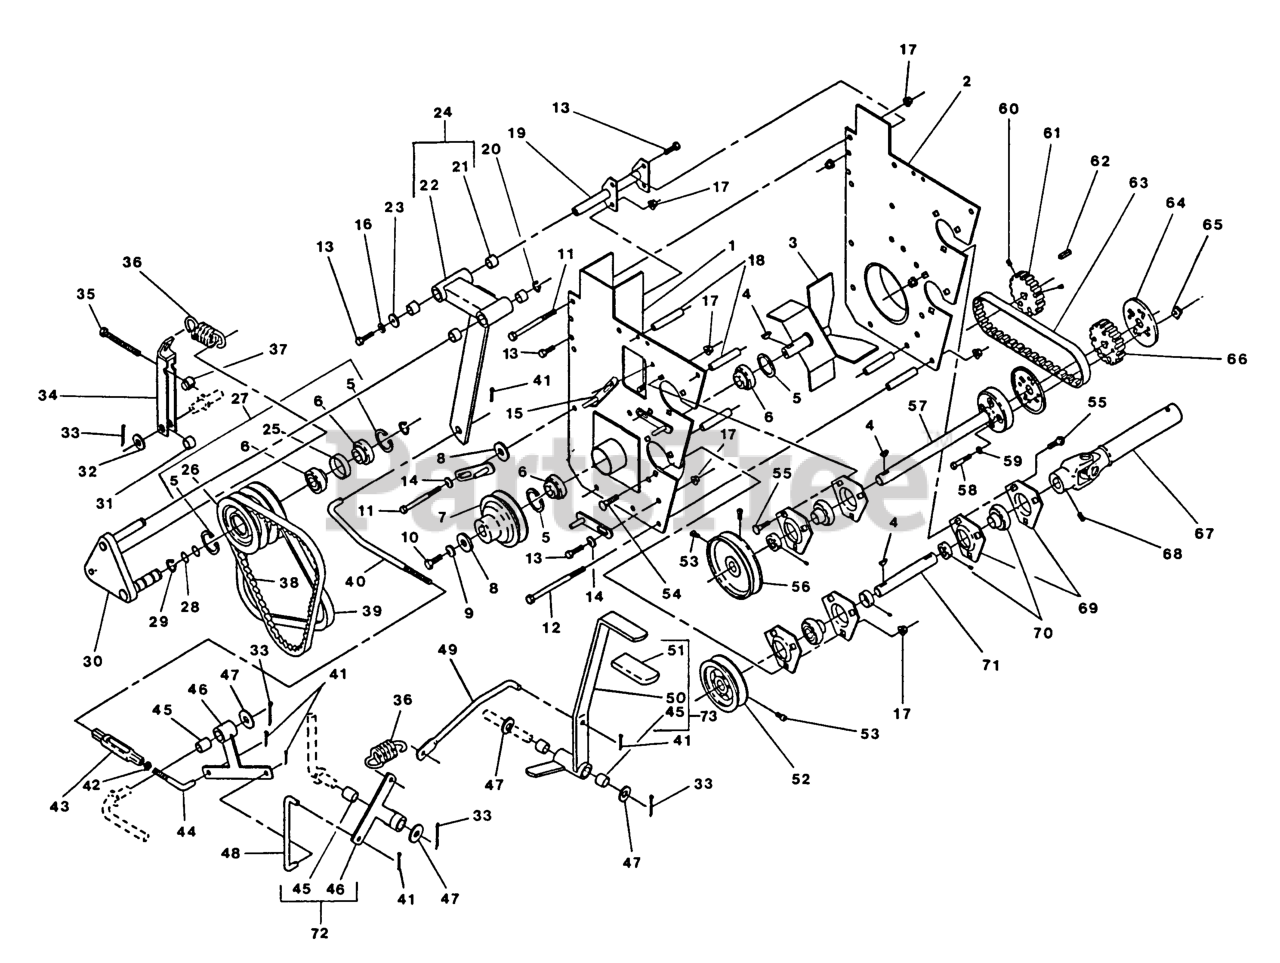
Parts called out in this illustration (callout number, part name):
2	WLD,PANEL FRONT
4	KEY-WOODRUFF
6	BEARING
12	SCREW-HH
14	WASHER-SPRING
16	WASHER-LOCK
22	Control Wldm't - Tmfr. Sheave
24	CNTRL ASSY,TRANS SHV
25	SPACER,TRANSFER BEARING
28	O-RING,
36	SPRING,BELT TENSION
37	SWIVEL,BELT TENSION
38	BELT,B SIZE 43.5
39	BELT,SECONDARY DRIVE
40	ROD,PTO LOW RH THD
44	ROD,PTO RH LOW LH THD
45	SLEEVE-BEARING
49	ROD,PTO UPPER
51	GRIP-LEVER
52	SHEAVE,5.5 B
53	SCREW-SET
56	SHEAVE,7 B
59	WASHER-LOCK
63	BELT,DRIVE POSITIVE
65	NUT,RETNR UTYP 1/4-20
69	HOUSING-FLANGE
70	BEARING,W/COLLAR
71	JACKSHAFT,PTO
